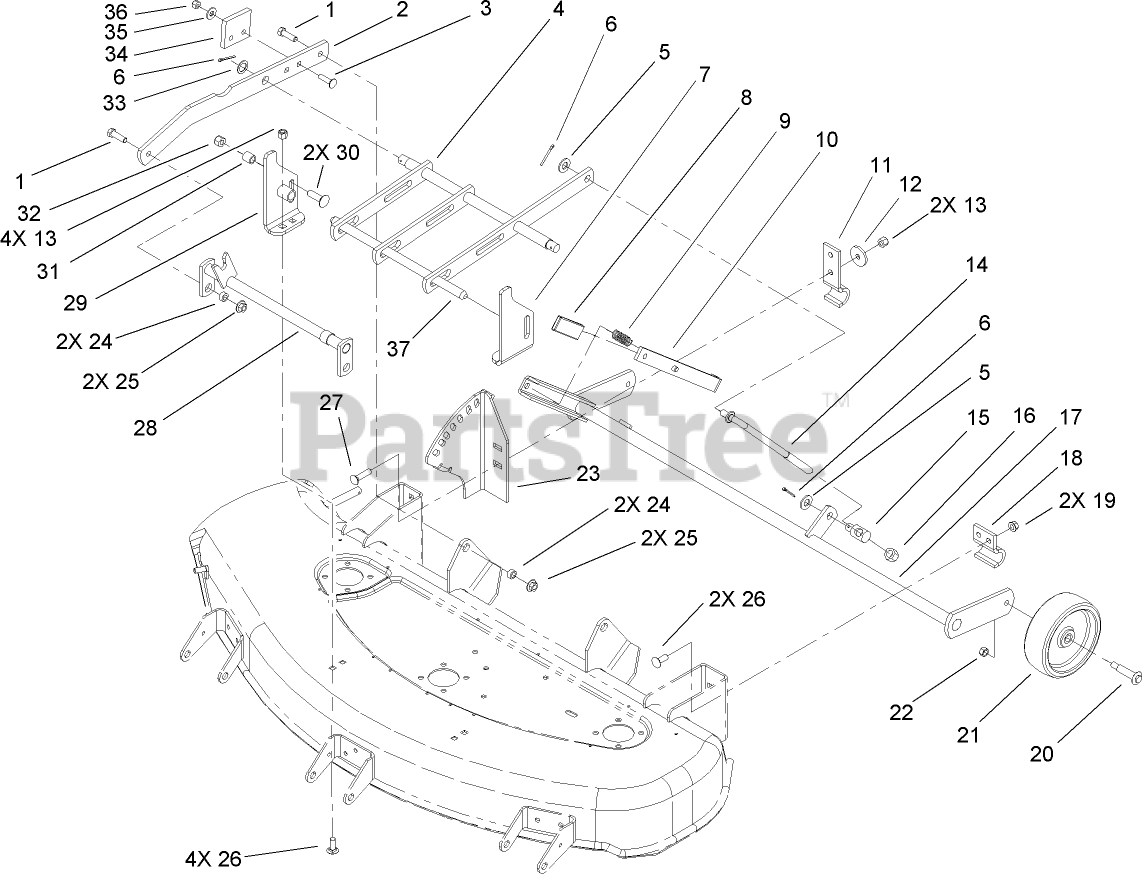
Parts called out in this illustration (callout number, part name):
1	SCREW-HH
2	BAR-DRAFT
3	SCREW-CARR
4	BAR-LEVELER ASM
5	WASHER-FLAT
6	PIN-COTTER
7	BRACKET-FRONT DECK, LH
9	SPRING-COMPRESSION
10	LEVER ASM-HOC
11	BRACKET-PIVOT
12	WASHER-SUPPORT
13	NUT-LOCK, NI
14	ROD-ADJUSTMENT
15	TRUNNION
16	NUT-LOCK, NI
17	WHEEL SUPPORT ASM
19	NUT-FLANGE
20	BOLT-SHOULDER
21	WHEEL
23	QUADRANT ASM
24	SPACER
26	BOLT-CARR
27	SCREW-CARR
28	HITCH ASM
29	BRACKET-FRONT DECK, RH
30	BOLT-CARR
31	SPACER
32	NUT-LOCK, NI
33	WASHER-FLAT
34	BUMPER
35	WASHER-FLAT
36	NUT-LOCK, NI
37	SHAFT-FRONT
